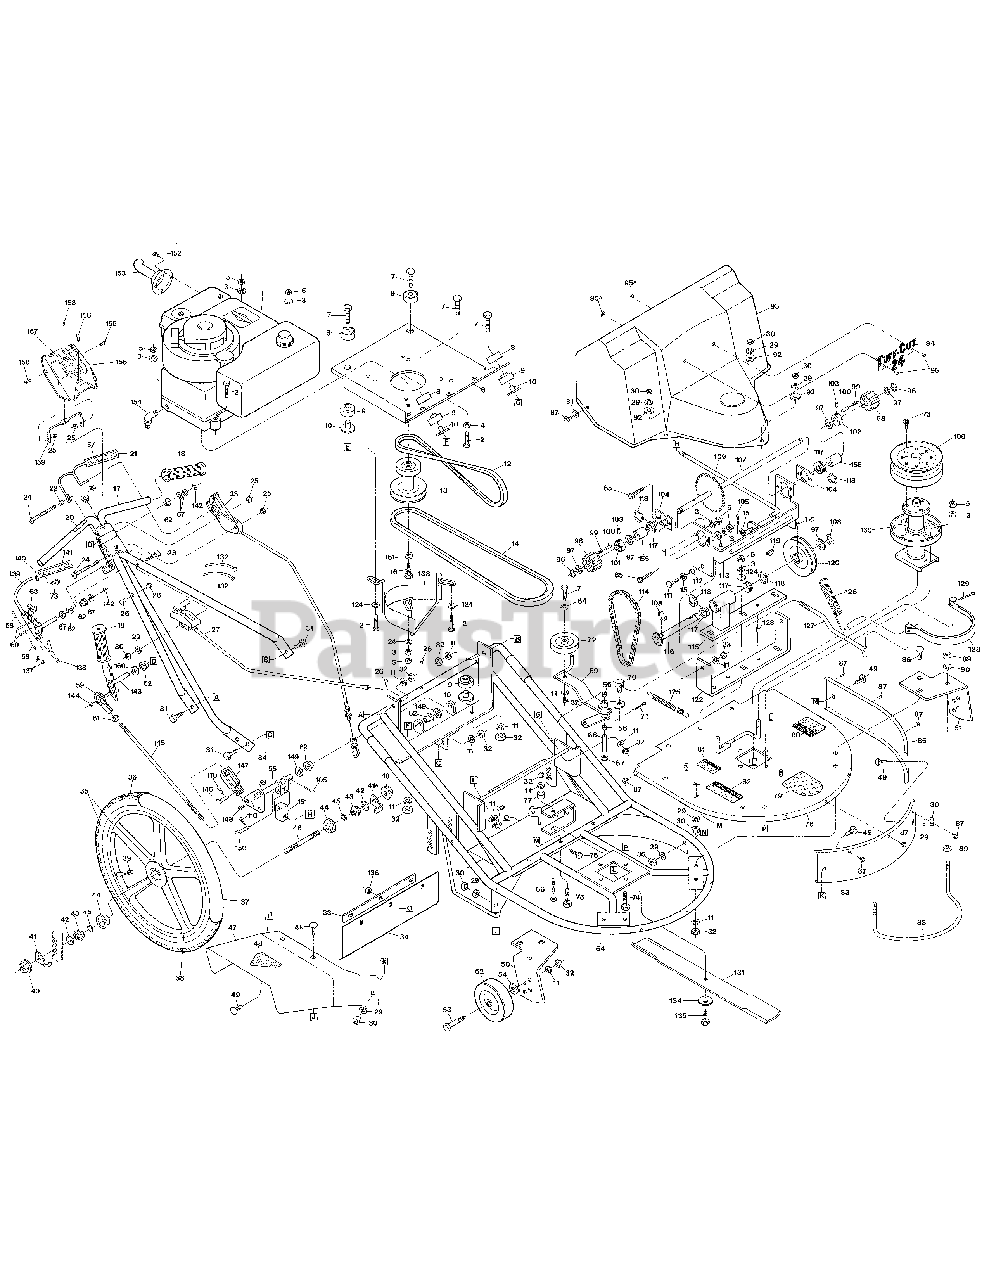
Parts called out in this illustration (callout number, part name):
1	ENGINE, BRIGGS & STRATTON 8 HP
2	SCR-HH 5/16-18X1.75
3	WASHER-LK .312
4	WASHER-.88X312X.08
5	NUT-HEX 5/16-18
6	BASE-ENGINE PNT
7	SCR-HH 3/8-16X2.0 G5
8	REBOUND MOUNT-24"
9	LOAD CARRYING MOUNT-24"
10	TUB-SPACER 24"
11	WASHER-LK .375 @ DEPL
12	TRACTION-V BELT
13	PULLEY-ENGINE
14	BLADE-V BELT
15	WASHER-1.0X.438X.104
16	SCR-HH 7/16-20X1.25 G5
17	ASSM-HANDLEBAR INCL. 18 (2 GRIPS) & 20
18	GRIP-HANDLEBAR
19	PLUG-METAL CAP
20	DECAL-STARTING INST
21	ASSM-BLADE CONTROL HANDLE (INCL. 57)
23	CABLE-BLADE DRIVE (CABLE & LATCH)
24	SCR-PHP M10-24X4.0
25	NUT-HEX LOCK #10-24 PL
26	PLUG-HOLE (RECOIL START ENGINES ONLY)
27	SPEED CONTROL-ENGINE (CALBE & CONTROL)
28	SCR 1/4-20X1.5 PL CSHH GRADE 5
29	WASHER-LK .25
30	NUT-HEX 1/4-20
31	SCR-HH 3/8-16X.75 G5
32	NUT-HEX 3/8-16
33	BRKT-PROT TRAILER PNT
34	TRAILER-MOWER
35	ASSM-TIRE & WHEEL {36,37,38,39,40,42,43,44, 45,46}
36	TIRE-20 X 2.125
37	TUBE-20"
38	ASSM-20" RIM {40,42,43,44,45,46}
39	CAP-VALVE
40	NUT-HF/LK 3/8-24 WHIZ
41	TAB-WHEEL LOCK RH
41A	TAB-WHEEL LOCK LH
42	NUT-LOCK 3/8-24 PL
43	NUT-ACORN 3/8-24
45	BEARING-WHEEL
46	AXLE-WHEEL
47	CHUTE-DISCHARGE W/DECAL (INCL. 48)
48	DECAL-BLADE WARNING
49	SCR-CARR 1/4-20X.375
50	HANGER-RT WHL PNT
51	HANGER-LT WHL PNT
52	ASSM-TIRE&WHL FRONT
53	SCR-SHLDR 3/8-16X1.406
54	SPROCKET-21T
55	WELD-BELLCRANK PLATED
56	BEARING-SLEEVE
57	STICKER-BLADE BAIL
58	PIN-COTTER .09X.75
59	JOINT-BALL
60	PIN-CLEVIS .248X1.0
61	NUT-HEX/JAM 3/8-24
62	BUSHING-.62X.5X.43 FLNG
63	LATCH-TOGGLE
64	FRAME-24" WELD PNT
65	SCR-HHCS 5/16-18X7/8GR5
66	SCR-HH 3/8-16X4.5 G5
67	SHIM-WASHER
68	TUBE-PIVOT
69	ARM-IDLER W/BUSHINGS (INCL. TWO BEARINGS #56)
70	TRUNNION
71	PIN-COTTER .094X1.0
72	PULLEY-IDLER
73	SCR-SELFTAP 5/16-18X5/8
74	SCR-HHC 5/16-18X.75 GR 5
75	SCR-HH 5/16-18X2.25 GR5
76	SCR-HHC 5/16-18X.75 GR 5
77	SPACER-.625X.387X1.0
78	ASSM-24" DECK TOP (INCL. 79-82)
79	DECAL-LOGO 24"
80	DECAL-WARNING PROCEDURES
81	DECAL-CAUTION BELT COVER
82	DECAL-DANGER GUARD
83	WRAP-FRONT 24" PNT
84	NUT W/LKWASHER 10-24
85	WRAP-LH PNT
86	SCR-CARR 3/8-16X1.00
87	SCR-HW M10-16X.75 SELT DR
88	BUMPER-24" PNT
89	NUT-HEX JAM 1/2-13
90	WASHER-LK .5
91	WASHER-#10 TYPE B PLN
92	WASHER-FLAT 1/4 SAE
93	KIT-SVC 24" BELT COVER
94	PLATE-NAME TUFFCUT
95	RIVET-POPOP
95A	WASHER-RIVETING
96	RING-HEAVY EXT .575 ID
97	WASHER-1.0X.632X.03
98	ROLLER-DRIVE
99	SPRING-DOWEL RETURN
100	PIN-DOWEL 1/4"
101	RATCHET-RH MACH
102	RATCHET-LH MACH
103	PIN-ROLL 3/16 X 1.5
104	PLATE-BEARING PNT
105	PIN-COTTER 1/8-1.00
106	KIT-PULLEY W/SCRS TC II (INCL. 3 SCREWS, #73)
107	SHAFT-DRIVE POLISHED 24"
108	RING-RETAINING "E"
109	ROD-TRAC DR LINK PNT
110	CLIP-HITCH PIN #13 PL
111	SCR-HH 3/8-16X1.0 G5
112	SPACER-.390X.630X.281
113	BRKT-TRACTION DR PNT
114	CHAIN #35-46 PITCHES
115	BRKT-JACKSFT MTG PNT
116	JACKSFT-WELD HEAT TREAT
117	BEARING
118	RING-RETAINING EXTERNAL
119	KEY-HI PRO 1/8X1/2
120	PULLEY-WHEEL DRIVE
121	SCR-SET 1/4-20X1/4
122	BRKT-U CHANNEL PNT
123	PIN-ROLL 1/4X1/2
124	WASHER
125	SPRING-WHEEL OR RETURN
126	SPRING-SPINDLE BRAKE (WITH LINING)
127	ROD-BRAKE ENGAGEMENT
128	BRAKE BAND & LINING
129	PIN-COTTER 1/8X3/4
130	KIT-SPINDLE TUFFCUT I&II, INCL. PULLEY(#106) , SPINDLE MOUNTING HARDWARE
131	BLADE-24" TUFFCUT
132	TIE-RED
133	GUIDE-BELT PNT
134	WASHER-BELLEVILLE 3/8
135	SCR-HH 3/8-24 X 1.5" G8
136	NUT-H/LK 5/16-18
139	BAIL W/SPRING (INCL. 137 & 138)
140	ASSM-WHEEL DR HANDLE (INCL. 141)
141	STICKER-TRACTION BAIL
142	RING-RETAINING EXTERNAL
143	ASSM-WHL DR LEVER W/GRIP (INCL. 18)
144	RING-RETAINING EXTERNAL
145	LINK-HANDLE
146	PIN-CLEVIS
147	CLEVIS (PLATED)
148	SCR-PHP 10-24X.625
149	WASHER-#.88X.51X.063
150	PIN-CLEVIS
151	ADJ-BLOCK PLATED
152	SCR-SELF TAP
153	PIPE-EXHAUST EXT PNT
154	ELBOW-90 ST 3/8"NPT
156	SHROUD-CNTRL W/DECAL (INCL. 157)
157	STICKER-OPER INST
158	SCR-PH PLPS 3/16-24X1/2
159	BRACE-PANEL
160	NUT-HFLK 3/8-16
161	WASHER-LK 7/16 MD SPR PL
